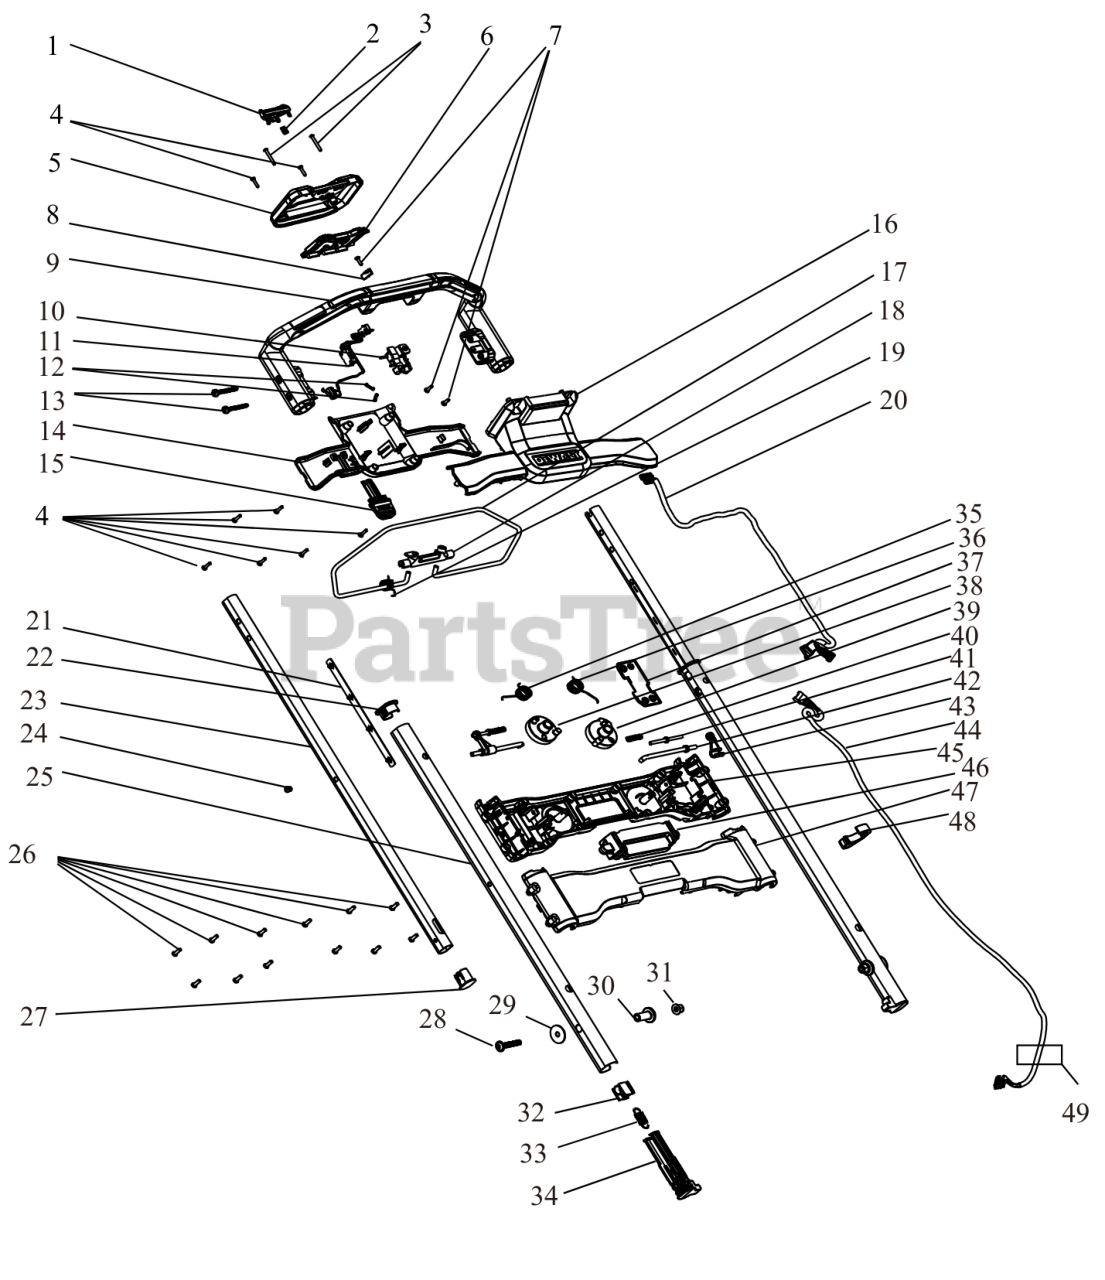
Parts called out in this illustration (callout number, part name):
1	BUTTON
2	SPRING
3	SCREW
5	COVER
6	CONTROL
8	BUTTOM
9	HANDLE SA
10	SWITCH
11	WIRE HARNESS
13	SCREW M6X45-T30-THD FRM
14	COVER
16	SWITCH COVER
17	CATCH
20	SPRING TORSION
21	STRIP
22	SLEEVE
23	TUBE UPPER
25	TUBE LOWER
26	SCREW M4.55X16 T20-PLAS THD FRM
27	SLEEVE
29	WASHER
30	SCREW
33	SPRING
35	SPRING
36	SPRING
37	SPRING
40	SPRING
43	HOLDER
44	HARNESS
45	COVER
46	BUTTON
47	COVER
49	GRASSBAG
50	FRAME
51	CHUTE
54	SPACER
55	SCREW 1/4-10 x .750
56	SUPPORT
57	BRACKET
58	LOCK-NUT
61	SPRING
62	BRACKET
63	SUPPORT
64	BRACKET
65	SHIELD
66	INSERT
67	FLANGE LOCK NUT
68	WHEEL 9X1.5
69	AXLE REAR
70	SPRING
74	AXLE FRONT
76	WHEEL SA
77	PLATE
79	BLADE MOUNT
80	BLADE MOUNT
81	WASHER
83	CUTTER DECK
87	SPRING
88	MOTOR SA
89	PCB SA
90	CONNECTOR
91	BAFFLE
92	HARNESS
93	HARNESS
94	MOTOR COVER
95	HOUSING
99	BUSHING
100	COVER
103	SA HANDLE PNL KIT PUSH-BLACK
104	LABEL
866	60V BATT FLEXVOLT 3AH/9AH DCB609
871	CHARGER
